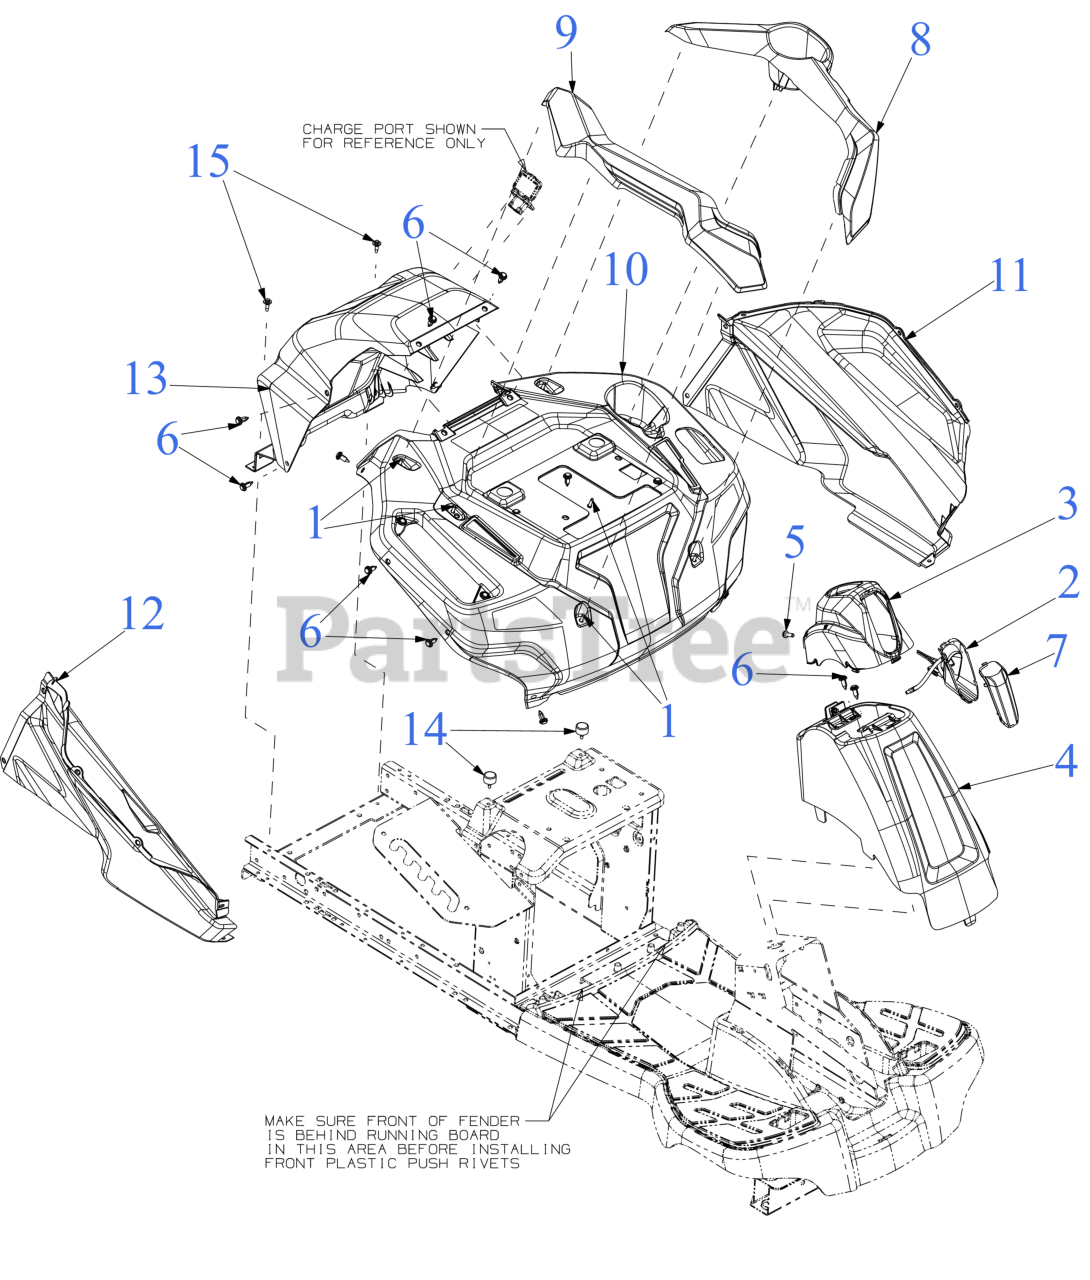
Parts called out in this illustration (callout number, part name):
1	SCREW, #8-16X.750 PH
2	LED HEADLIGHT HARNESS ASSEMBLY
3	COLUMN CAP (LIBERTY RED)
4	COLUMN COVER (LIBERTY RED)
5	SCREW 1/4-20X.75
6	PLASTIC RIVET
7	LED HEADLIGHT LENS
8	FENDER TRIM (LH)(BRIGHT SILVER)
9	FENDER TRIM (RH)(BRIGHT SILVER)
10	FENDER
11	BODY PANEL (LH)
12	BODY PANEL (RH)
13	REAR COVER
14	BUMPER .62 DIA x .50
15	SHOULDER SCREW M6-1 .368 X.115
